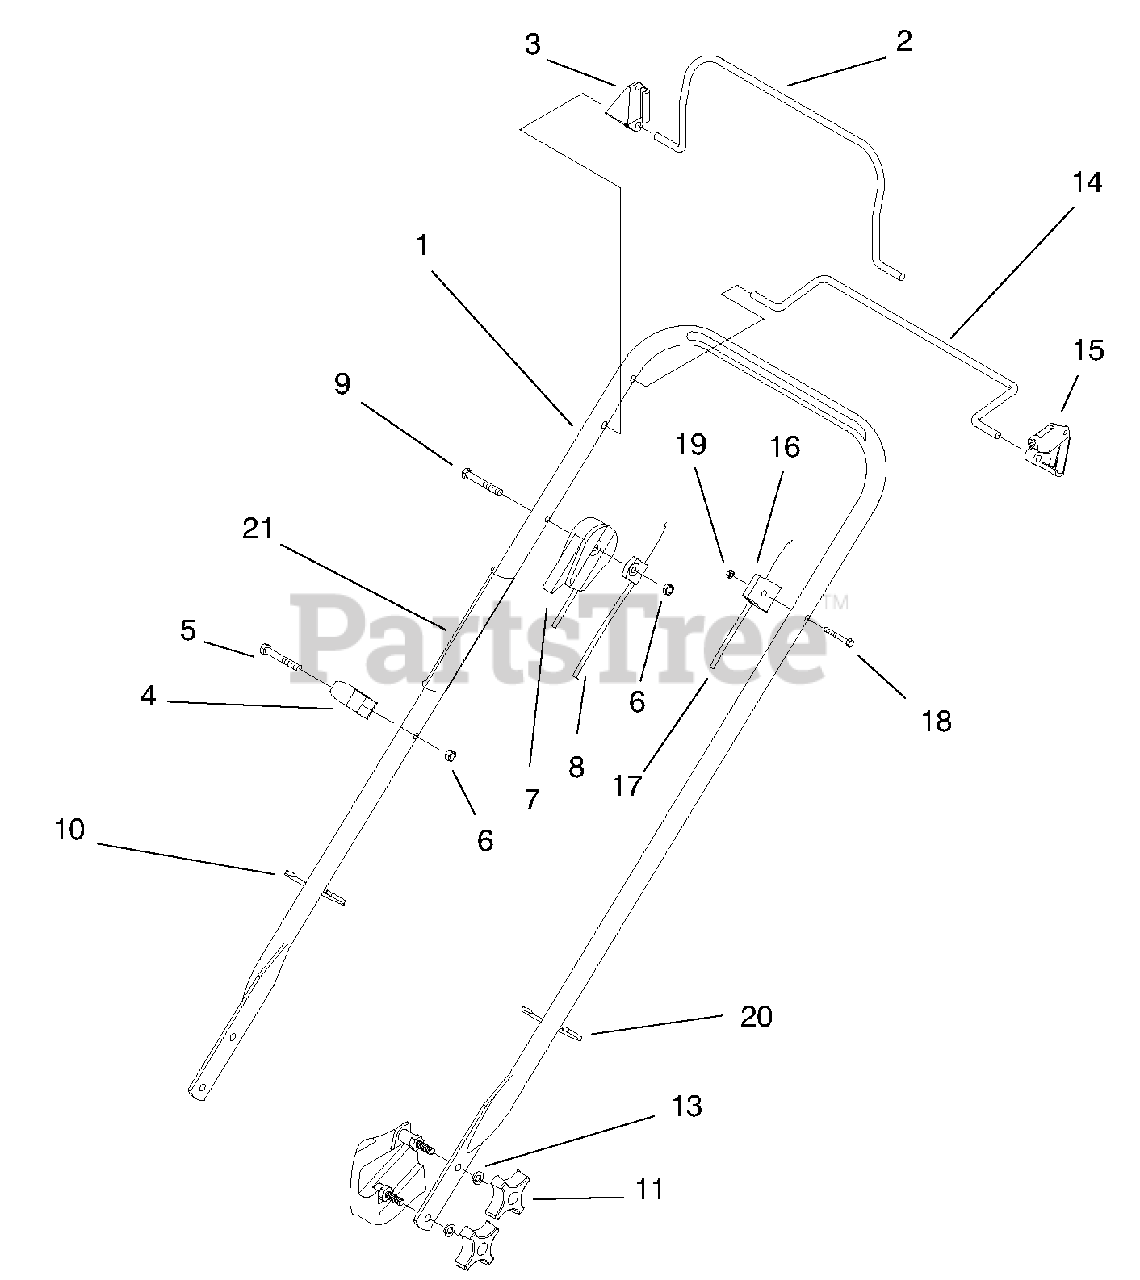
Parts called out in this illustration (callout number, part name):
2	Bail-Flywheel Brake
3	Stop-Pivot
4	Guide-Rope
5	Screw-HH
6	Nut-Lock Insert
7	Cable Throttle
8	Cable-Flywheel Brake
9	Screw-HH
10	Tie-Cable
11	Knob
13	Washer-Lock
14	Bail-Control
15	Stop-Pivot
16	Anchor-Cable
17	Cable Traction
18	Screw-HH
19	Nut-Lock (Insert)
20	Tie-Cable
21	Decal-Operation
